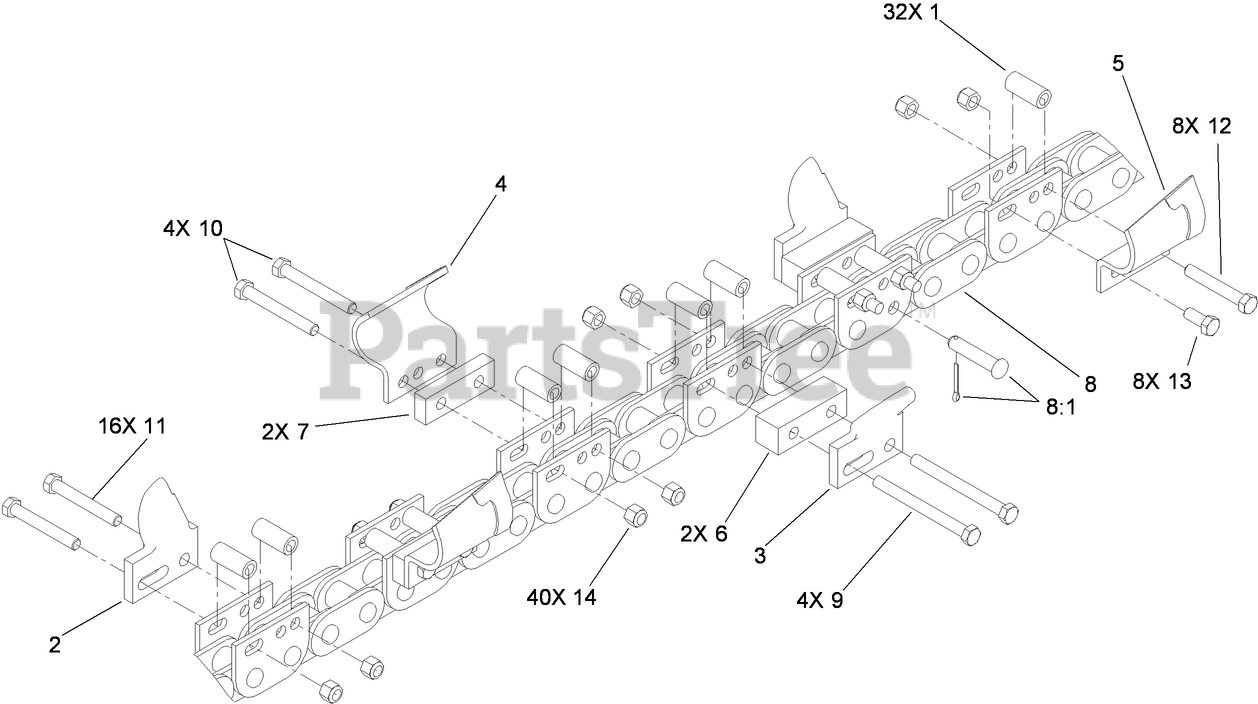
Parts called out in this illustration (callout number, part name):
1	SPACER-TUBE
2	TOOTH- ROCK, LH
3	TOOTH-ROCK, RH
4	TOOTH-SOIL, LH
5	TOOTH-SOIL, RH
6	SPACER-CUT, 6 INCH
7	SPACER-CUT, 5 INCH
8	CHAIN-BARE, 40 STATION
8:1	PIN-CONNECTING,
9	SCREW-HH
10	SCREW-HH
11	SCREW-HH
12	SCREW-HH
13	SCREW-HH
14	NUT-LOCK
